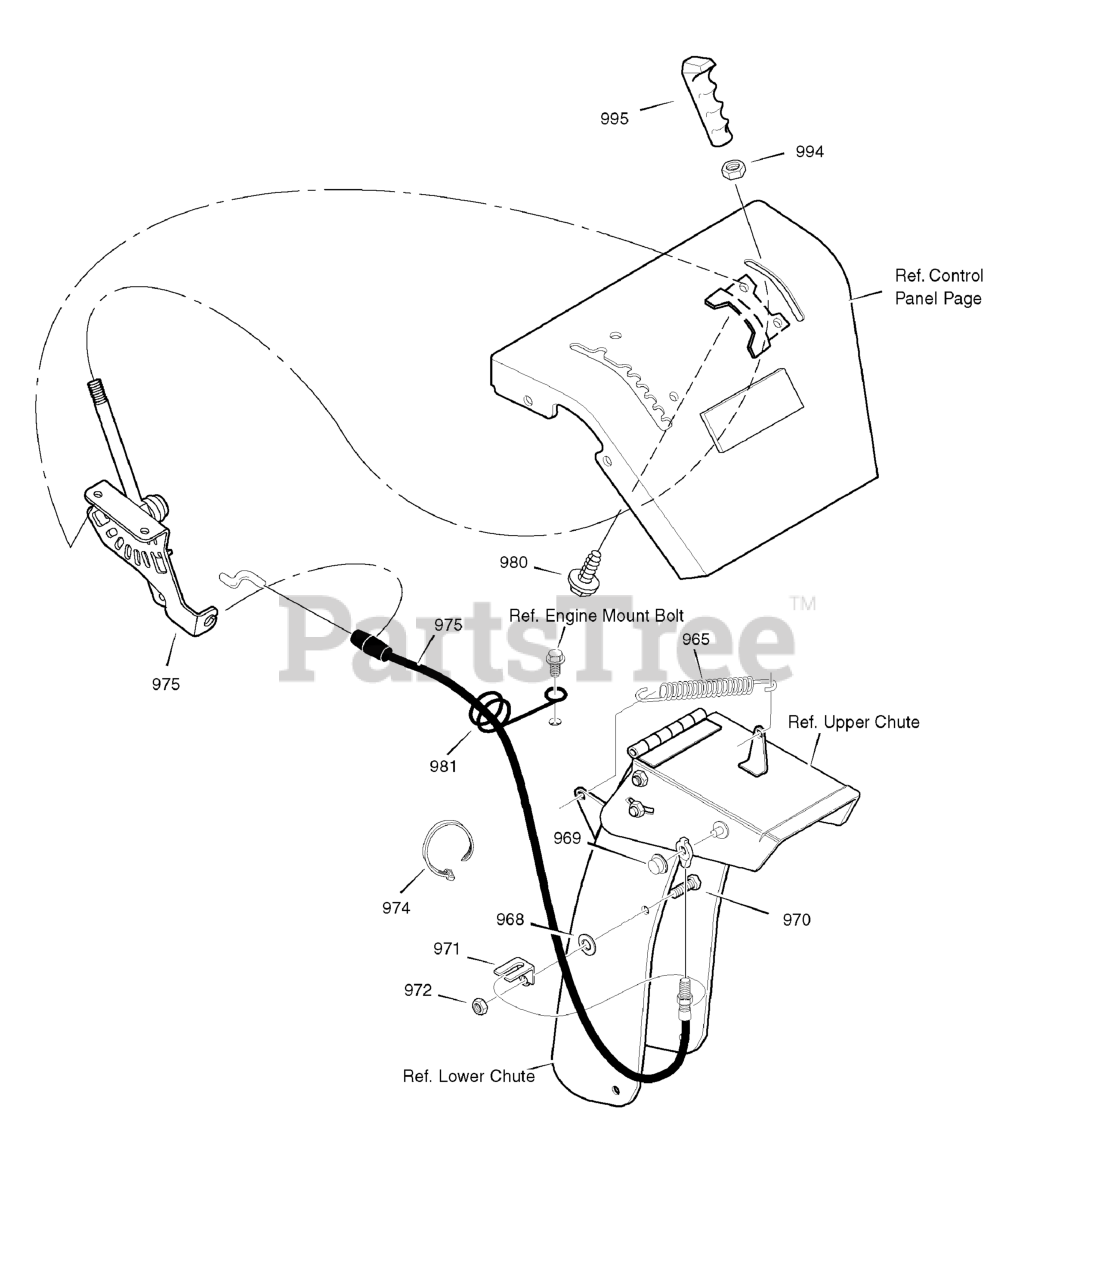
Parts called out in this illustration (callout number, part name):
965	TENSION SPRING
968	FLATWASHER
969	PUSH NUT
970	SCREW
971	BRACKET, CABLE CHUTE
974	TIE, CABLE
975	LEVER & CABLE, CHUTE DEFLECTOR
980	SCREW
981	WIRE FORM, REMOTE CHUTE CABLE
